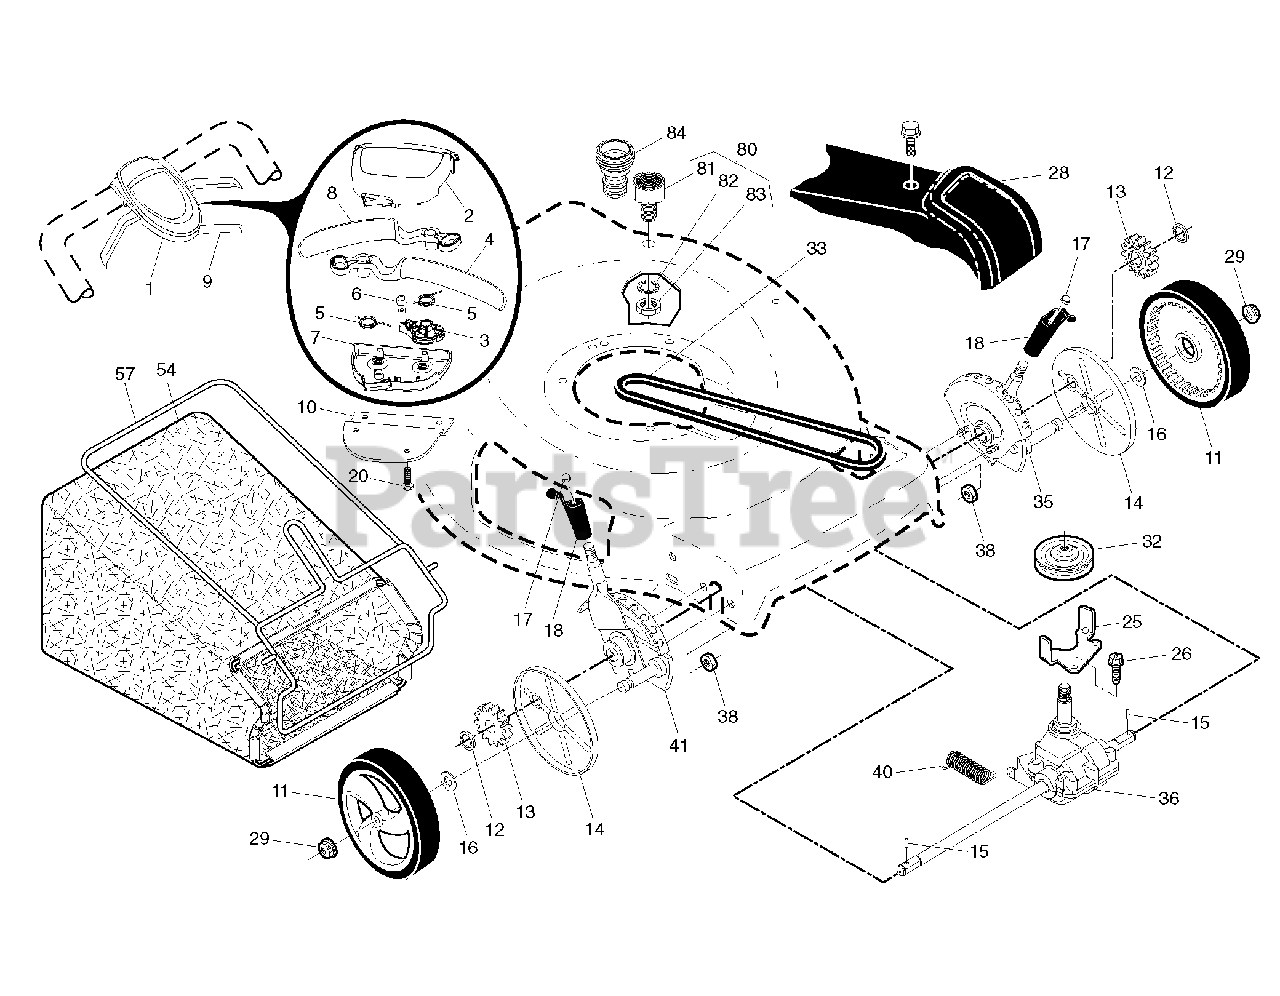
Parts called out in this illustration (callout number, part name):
3	CAM.GEN2.DUAL.TRIGGER
4	CAM.VSC.DRIVE.CABLE
5	SPRING, DRIVE CONTROL
6	BUSHING.CONTROL.CAM
10	BRACKET.DRIVE.CONTR.GEN2.BLACK
12	E-RING 7/16 RE
13	PINION.14.TEETH.FGD
14	COVER.DUST.WHEEL
15	PAWL, DRIVE
16	WASHER FLUT
20	SCREW, PHILLIPS HEAD 10 X 5/8
25	BRACKET.BELT.GUIDE.22+FGD.BZP
29	NUT.HEX.FLANGE.3/8-16.LOCKNUT
32	RP PULLEY.DRIVE.EZ
38	NUT.HEX.FLANGE.1/4
57	FRAME.GBAG.22PLUS
80	KIT.WASH-OUT.PORT
81	FITTING, HOSE, WATER WASHOUT
82	WASHER.LOCK.INTERNAL.TOOTH
83	LOCKNUT.HEX.WITH.O-RING
